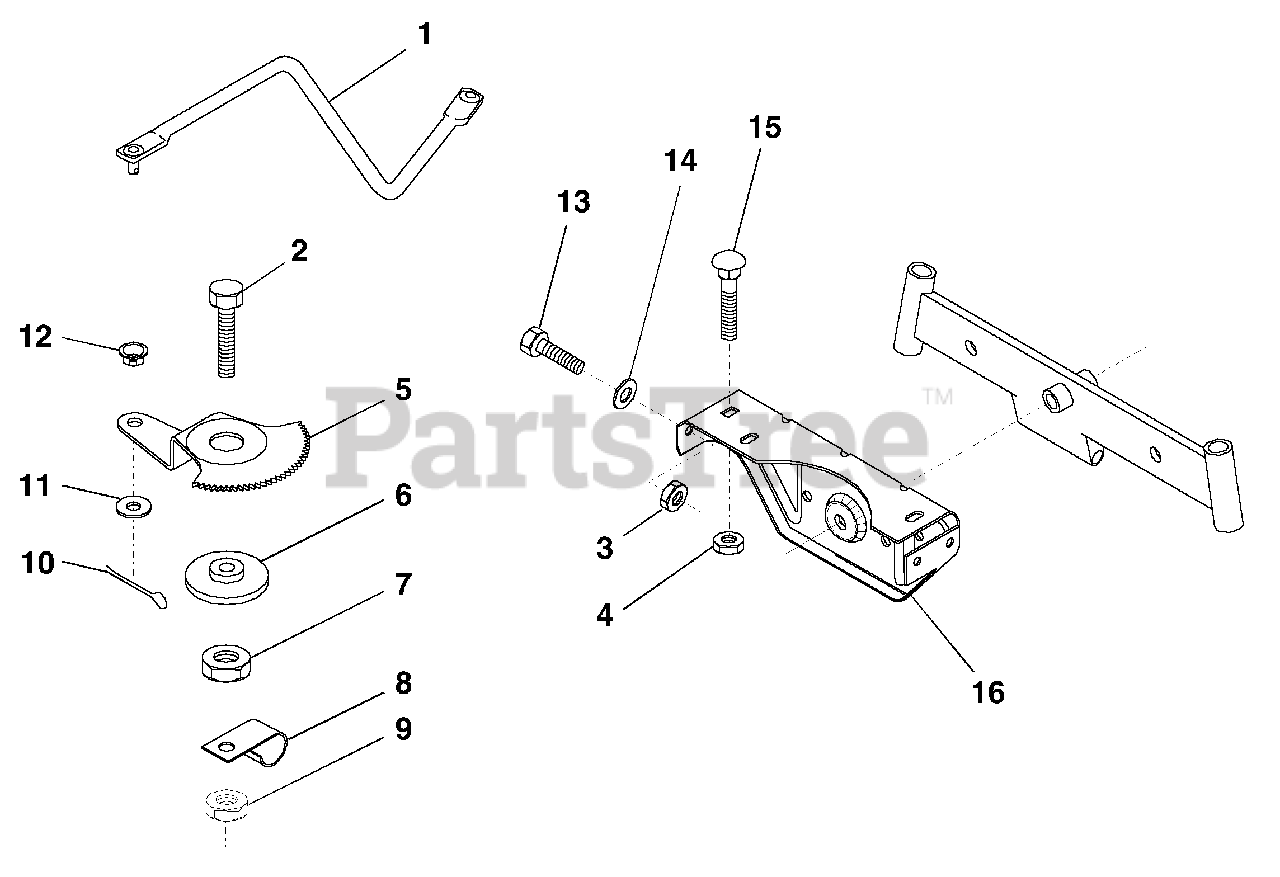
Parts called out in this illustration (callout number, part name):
1	Link, Drag
2	Bolt, Fin Hex 1/2-13 x 1-3/4
3	Nut, Crownlock 5/16-18
4	Nut, Crownlock 3/8-16 UNC
5	Gear, Sector
7	Nut, Heavy Hex Top Lock 1/2-13 UNC
8	Clip, Insulated
9	Nut, Crownlock 3/8-16
10	Pin, Cotter 1/8 x 3/4
11	Washer, 13/32 x 13/16 x 16 Ga.
13	Bolt, Hex Hd. 5/16-18 UNC x 3/4
14	Washer 11/32 x 7/8 x 16 Ga.
15	Bolt, Carriage 3/8-16 UNC x 3/4
16	Support, Front Axle
